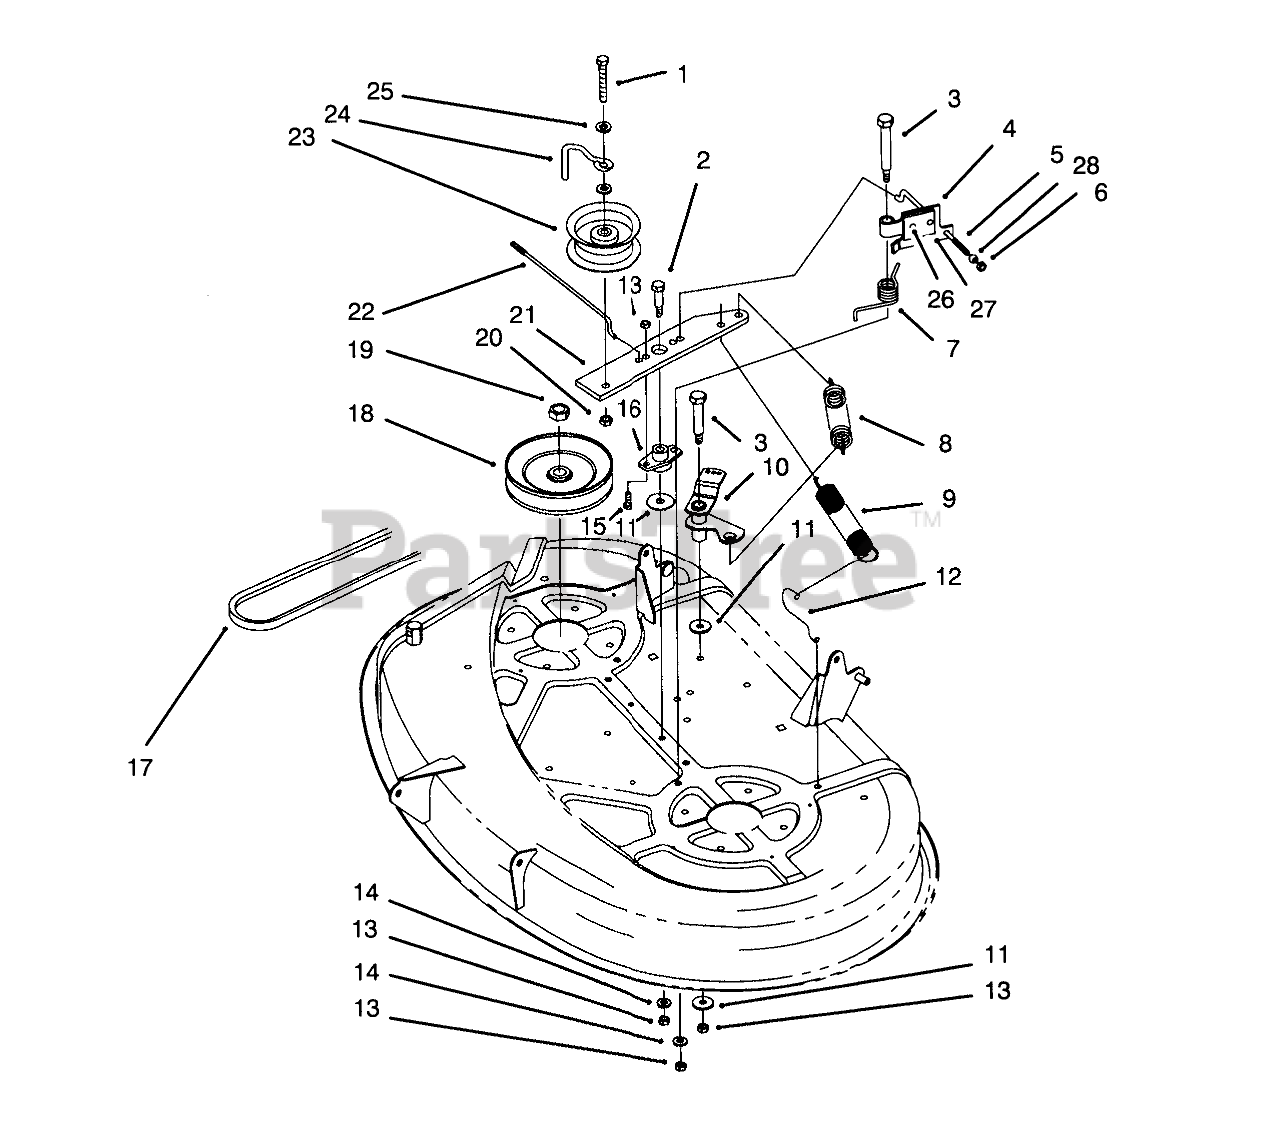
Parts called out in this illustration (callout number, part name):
1	SCREW-HH
2	SCREW-SHOULDER, HH
3	BOLT-SHOULDER
4	Brake-Deck (Incl. Ref. #26 & 27)
5	ROD-BRAKE, DECK LH
6	NUT-LOCK, NI
7	SPRING-TORSION
8	SPRING-DECK, ENGAGEMENT
9	SPRING-EXTENSION
10	Bellcrank
11	WASHER-FLAT
12	HOOK-RETURN, SPRING
13	NUT-LOCK, NI
14	WASHER-PLAIN
15	SCREW-HH
16	BUSHING-ARM, IDLER
17	BELT-V
18	PULLEY
19	NUT-HEX
20	NUT-LOCK, NI
21	Arm-Idler
22	ROD-BRAKE, DECK RH
23	PULLEY-IDLER, FLAT
24	GUIDE-IDLER, BELT
25	WASHER-FLAT
26	RIVET-BLIND
27	PAD-BRAKE
28	BALL-SWIVEL, STOP
